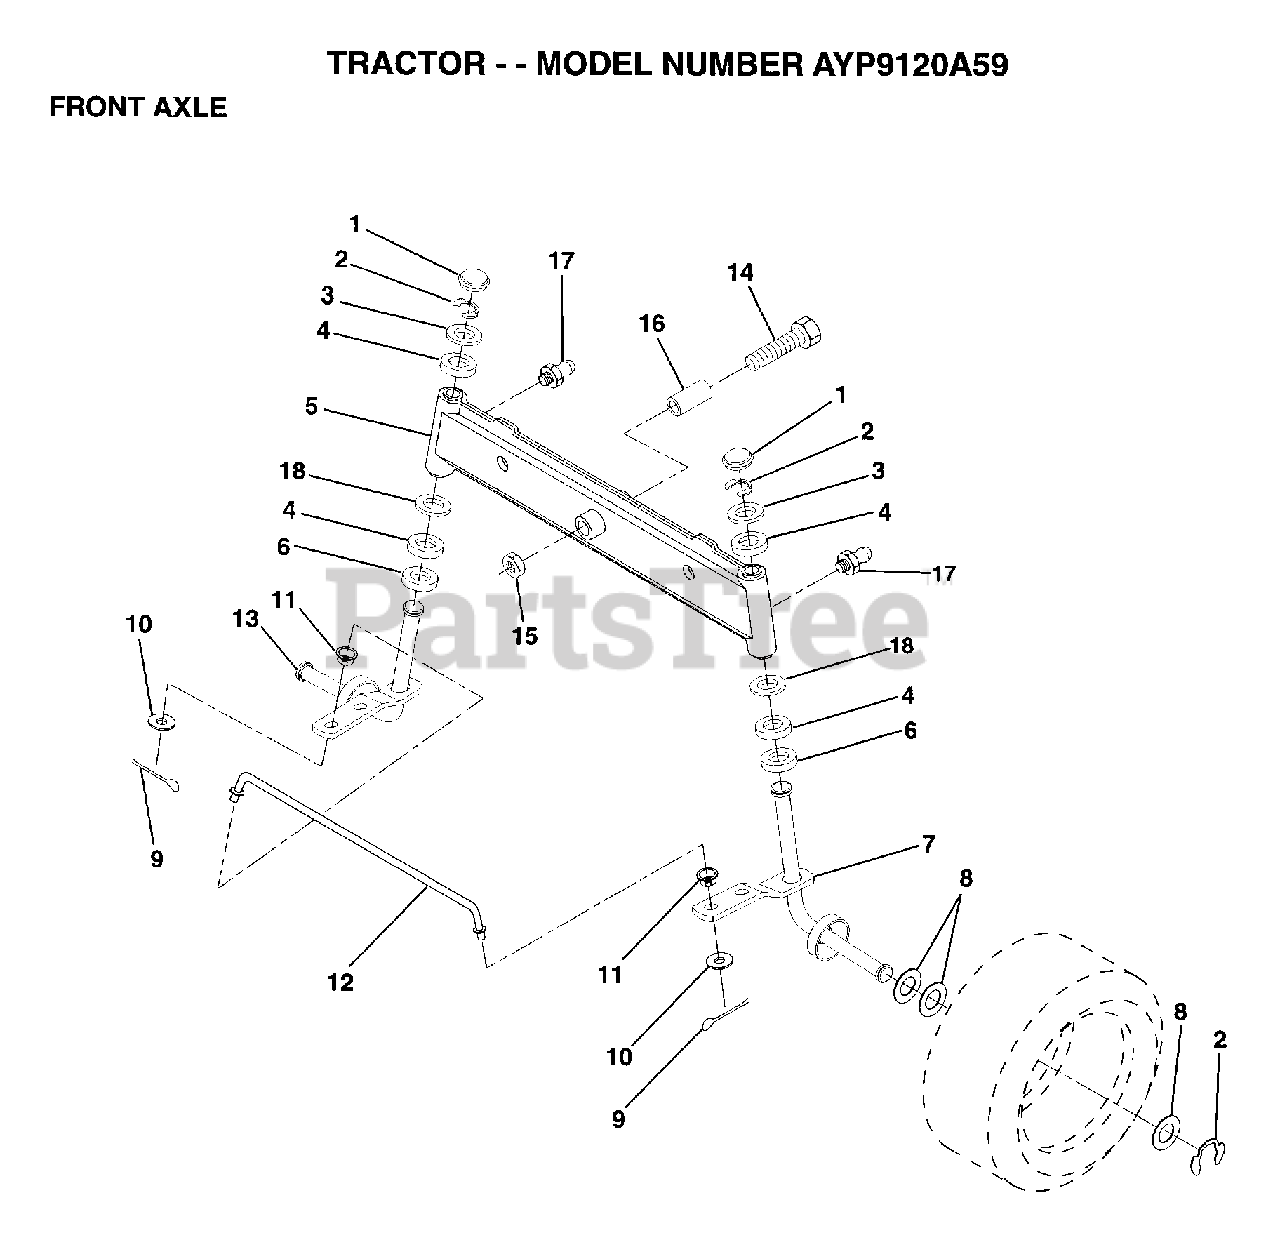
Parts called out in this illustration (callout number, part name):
1	CAP
2	RING
3	WASHER
4	COL. SRTG. BEAR.
5	AXLE ASM FRONT
6	WASHER .T
7	SPINDLE ASM RH
8	WASHER
9	COTTER PIN
10	WASHER
11	BUSHING.DRAGLINK
12	TIE ROD
13	SPINDLE ASM LH
14	BOLT HEX 5/8-11
15	"NUT-LOC,FLANGE LT"
16	BEARING
17	ZERK M
18	WASHER
